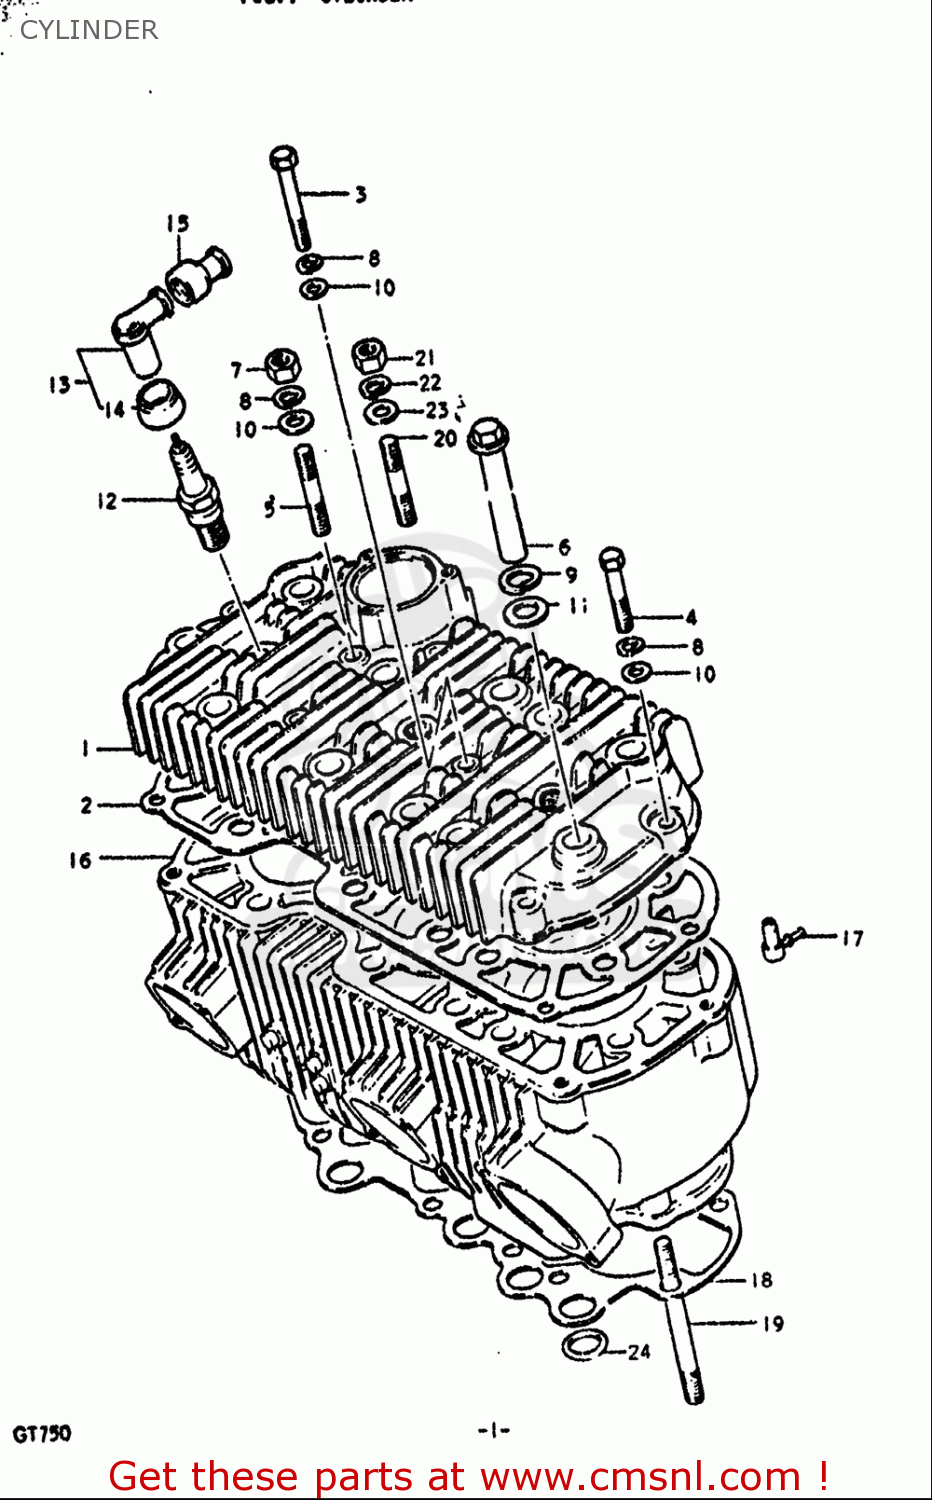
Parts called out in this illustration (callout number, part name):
2	GASKET,CYLINDER HEAD (NAS)
3	BOLT
4	BOLT
5	STUD BOLT
6	NUT
7	NUT
8	WASHER,LOCK
9	WASHER,LOCK
10	WASHER
11	GASKET(14X26X3) (NAS)
12	SPARK PLUG B7ES
13	CAP,SPARK PLUG
15	SEAL,HIGH TENSION CORD
17	UNION,OIL HOSE
18	GASKET,CYLINDER (NAS)
20	BOLT
21	NUT
22	WASHER,LOCK
23	WASHER
24	O RING(D:2.4,ID:21.8)
